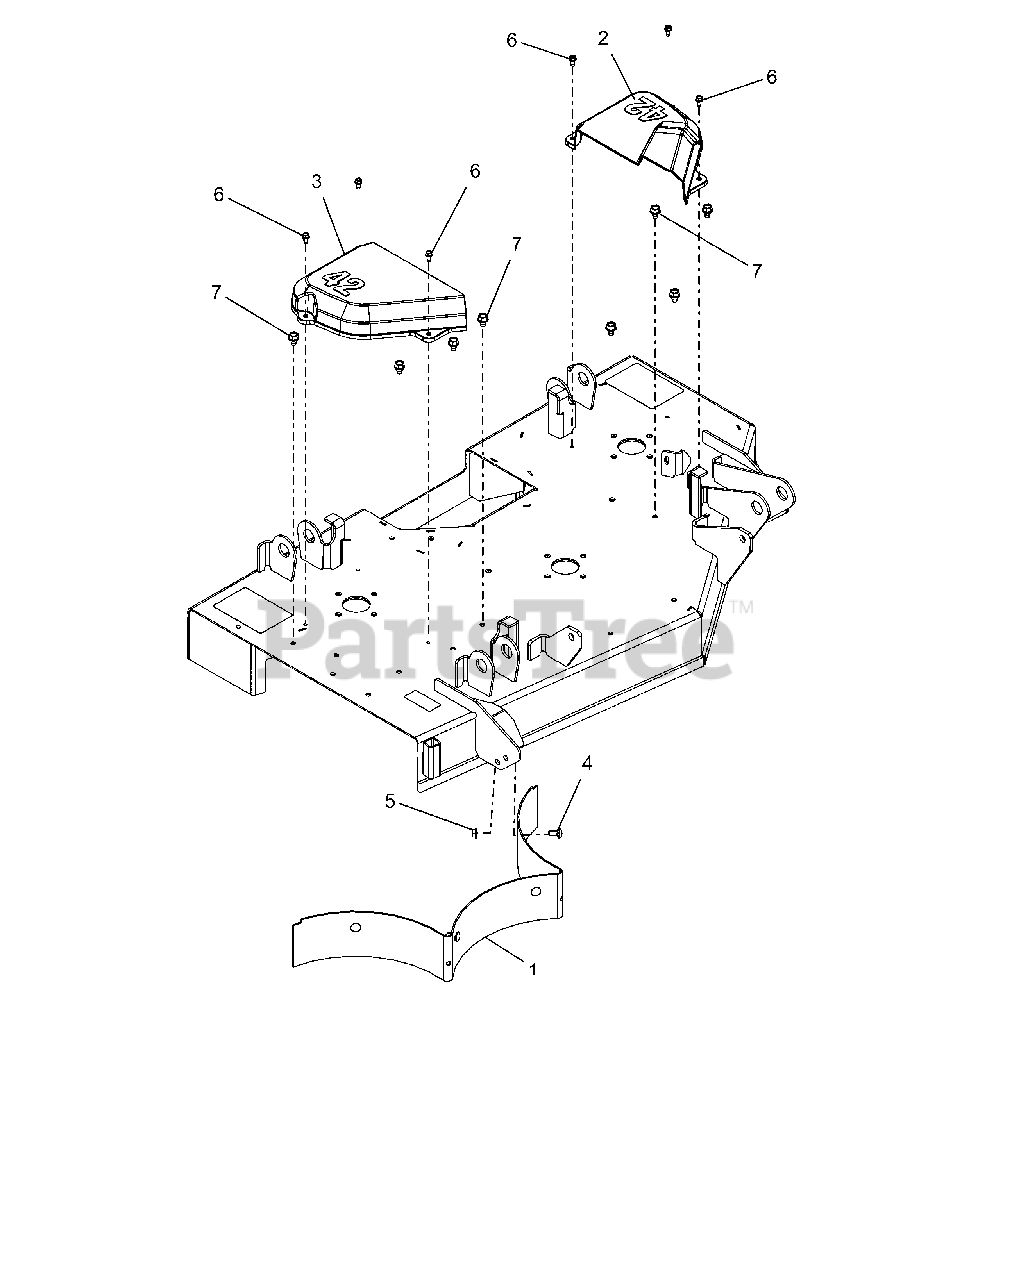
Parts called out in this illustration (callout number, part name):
1	BAFFLE, REAR 42
2	COVER, BELT 42" LH
3	COVER, BELT 42" RH
4	@BLT-RDHDSQNK .31-18X.75 G5YZ
5	@NUT-LK-TOP-FLG .31-18 YWZC
6	SCR-TAP .25-20X.50 HWH TR YWZ
7	@SCR-TAP .38-16X.50 HWH TR YWZ
